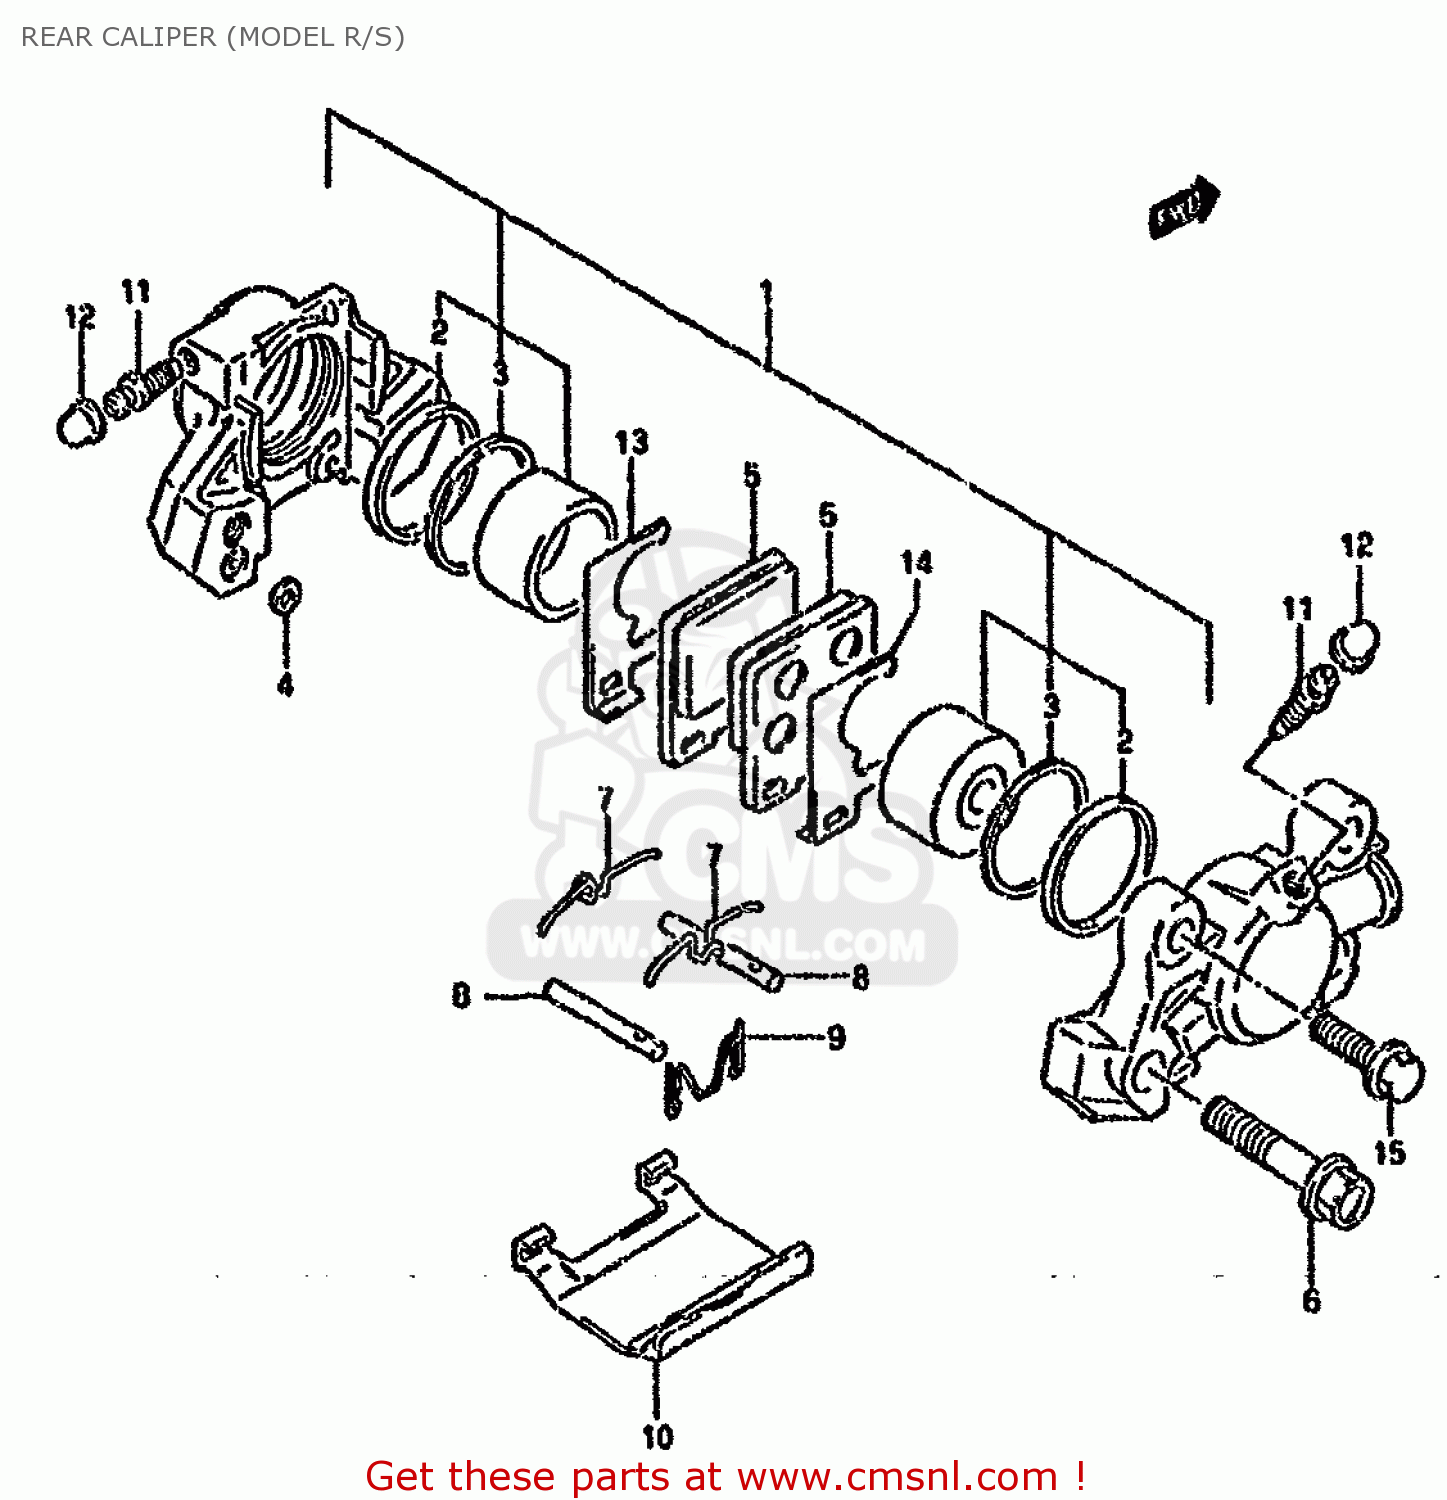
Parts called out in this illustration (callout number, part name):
1	PISTON SET
2	SEAL,PISTON
3	SEAL,WIPER
4	SEAL,JOINT
5	PAD,BRAKE
6	BOLT
7	SPRING
8	PIN,PAD
9	CLIP,PAD PIN
10	COVER
11	BLEEDER
12	CAP,BLEEDER PLUG
13	SHIM,INNER
14	SHIM,OUTER
15	BOLT
